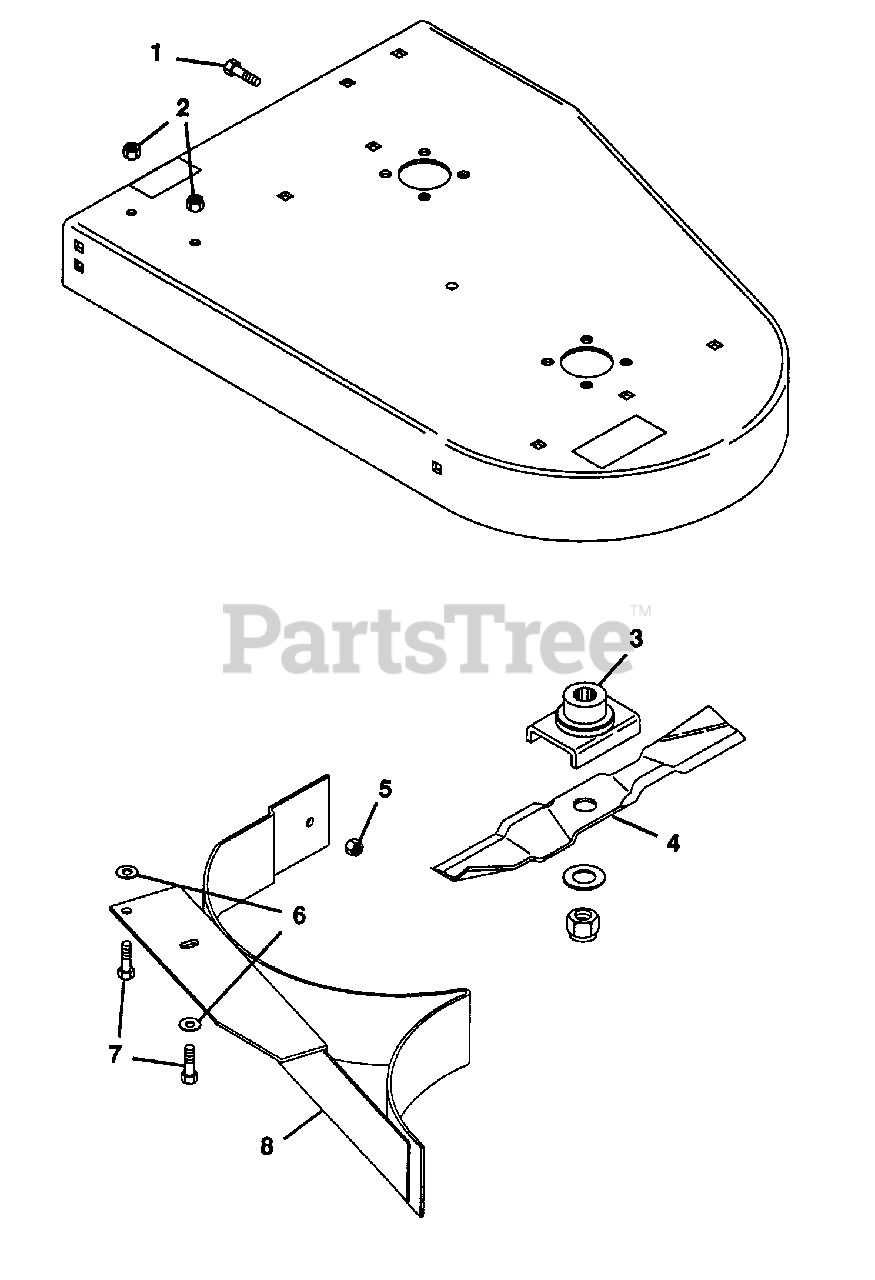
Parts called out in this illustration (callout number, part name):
1	Bolt, Hex 5/16-18 x.750
2	Nut, Lock 3/8-16
3	Weldment, Blade Cradle
4	Blade, Mulching 36" Mower
5	Nut, Lock 5/16-18
6	Washer, Flat .406 x.812 x .065
7	Bolt, Hex 3/8-16 x.75
8	Weldment, Mulching Baffle
